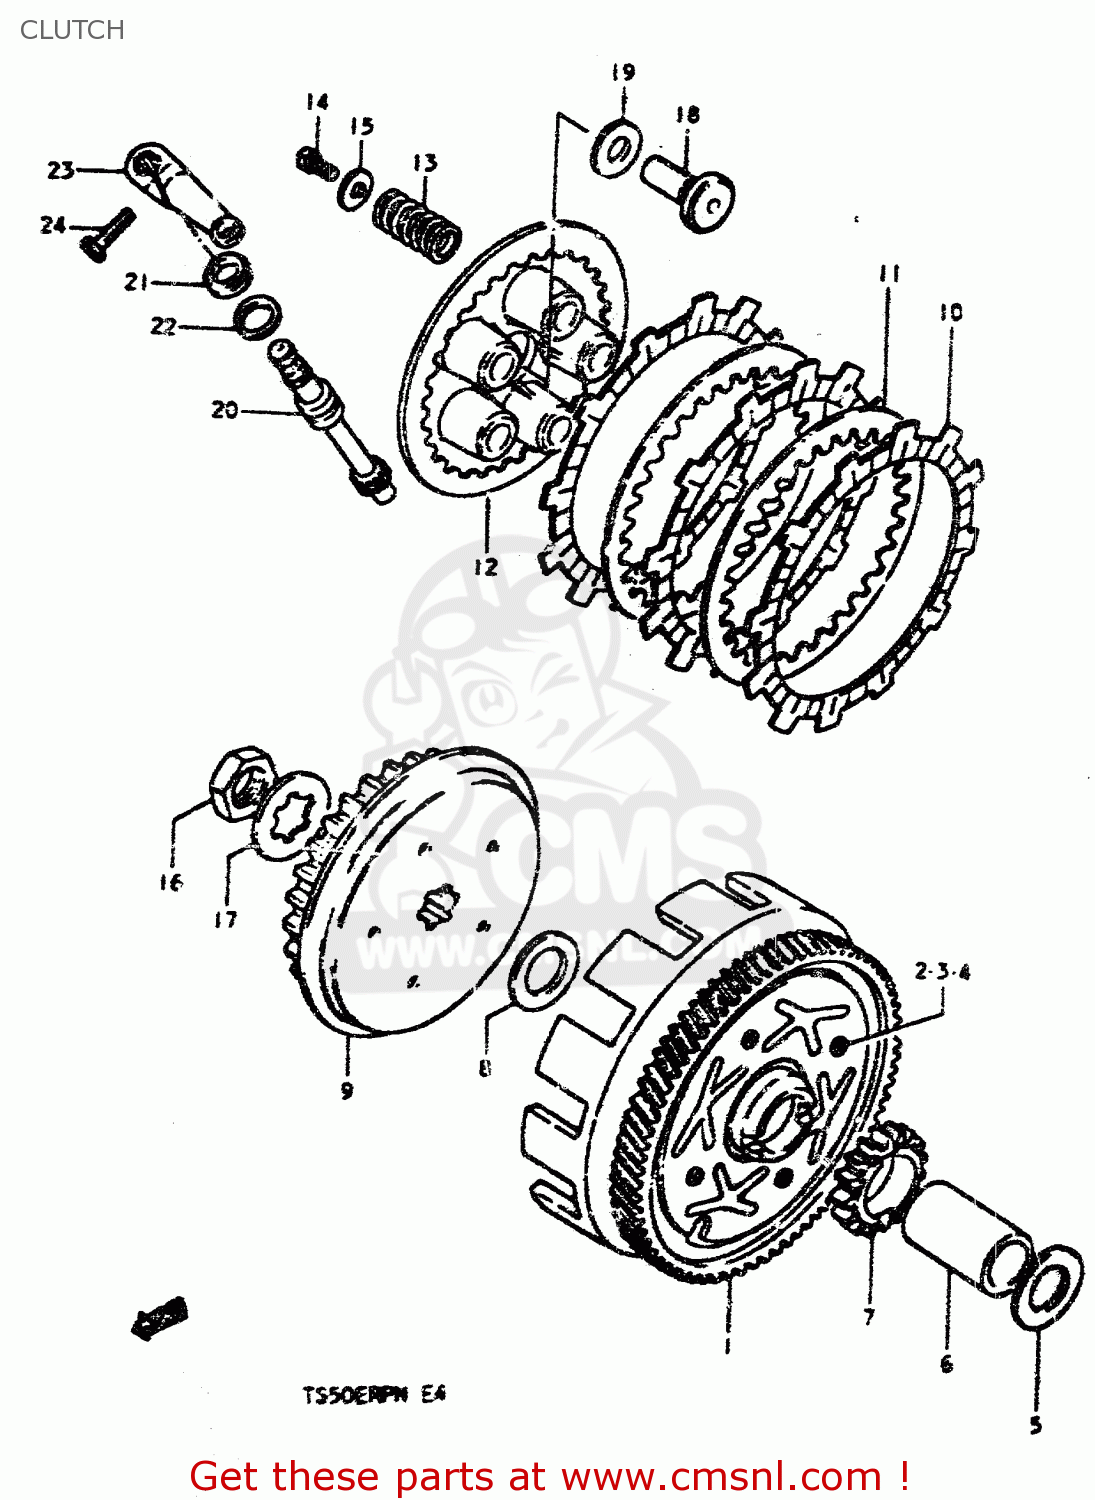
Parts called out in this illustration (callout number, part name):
1	GEAR ASSEMBLY,PRIMARY DRIVE
2	DAMPER,PRIMARY DRIVEN GEAR
3	PLATE
4	RIVET
5	THRUST WASHER
6	SPACER
7	GEAR,KICK STARTER DRIVE
8	WASHER
9	HUB,CLUTCH SLEEVE
10	PLATE,CLUTCH DRIVE
11	PLATE,CLUTCH DRIVEN (NAS)
12	DISC,CLUTCH PRESSURE
13	SPRING
14	BOLT(5X16)
15	WASHER (5.5X16X1.2)
16	NUT
17	WASHER,LOCK
18	RACK,CLUTCH RELEASE
19	BEARING(10X22X2.8)
20	PINION,CLUTCH RELEASE
21	OIL SEAL
22	WASHER (12X17X1)
23	ARM,CLUTCH RELEASE
24	BOLT, UPPER
